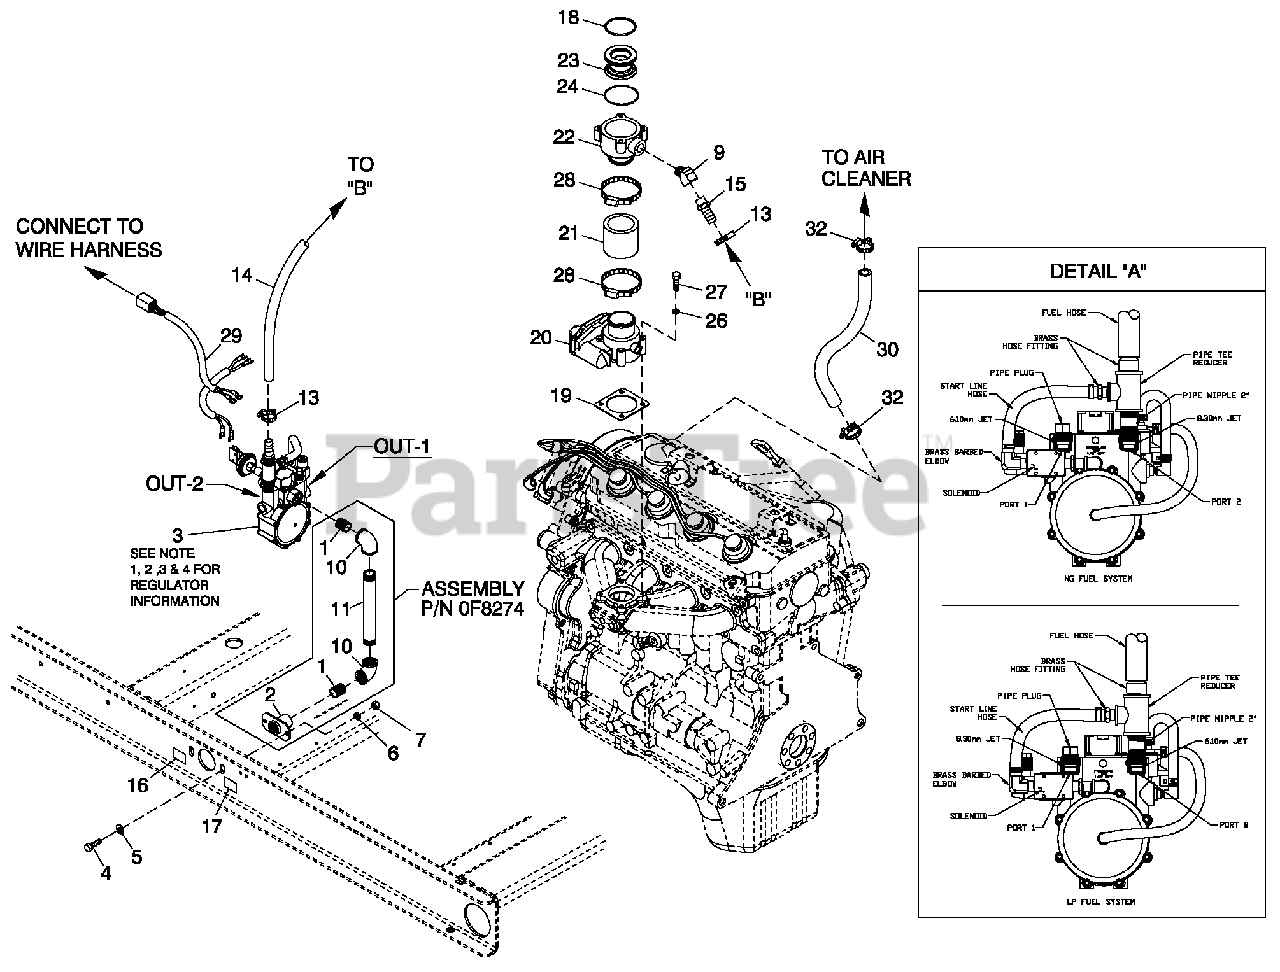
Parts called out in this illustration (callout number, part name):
1	NIPPE COSE 3/4 X 1.375
2	FANGE FUEL INLET
3	REGUATOR ASSY 2.4 (25KW)
4	SCREW HHC M8-1.25X 20 G8.8
5	WASHER FAT 5/16-M8 ZINC
6	WASHER OCK M8-5/16
7	NUT HEX M8-1.25 G8 CEAR ZINC
9	STREET EL 45D 1/2 NPT BRASS
10	ELBOW 90D 3/4NPT
11	NIPPLE PIPE 3/4 NPT X 7
13	CLAMP HOSE #10 .56-1.06
14	HOSE 3/4 ID SAE-30R2 (18" G)
15	BARBED STR 1/2 NPT X 3/4
16	DECAL INET PRESSURE
17	DECAL FUEL INLET NG(NATURAL GAS APPLICATION)
18	O-RING 45.63 ID X 2.62 WIDTH
19	GASKET BOSCH 32
20	ACTUATOR BOSCH 40 GOVERNOR (45K)
21	HOSE COOL 2 IN ID 20R4 (45K )
22	MIXER ACTUATOR 32MM MACHINED (25K)
23	VENTURI THROTTE 26MM (35 & 45K)
24	O-RING 47.625 ID X 2.38 WIDTH
26	WASHER LOCK M6-1/4
27	SCREW SHC M6-1.0 X 45 G12.9
28	CAMP HOSE #28 1.32-2.25
29	HARNESS CPL FUEL JUMPER
30	HOSE 3/8 ID SINGLE BRAID(18"G)
32	CLAMP HOSE #10.56-1.06
